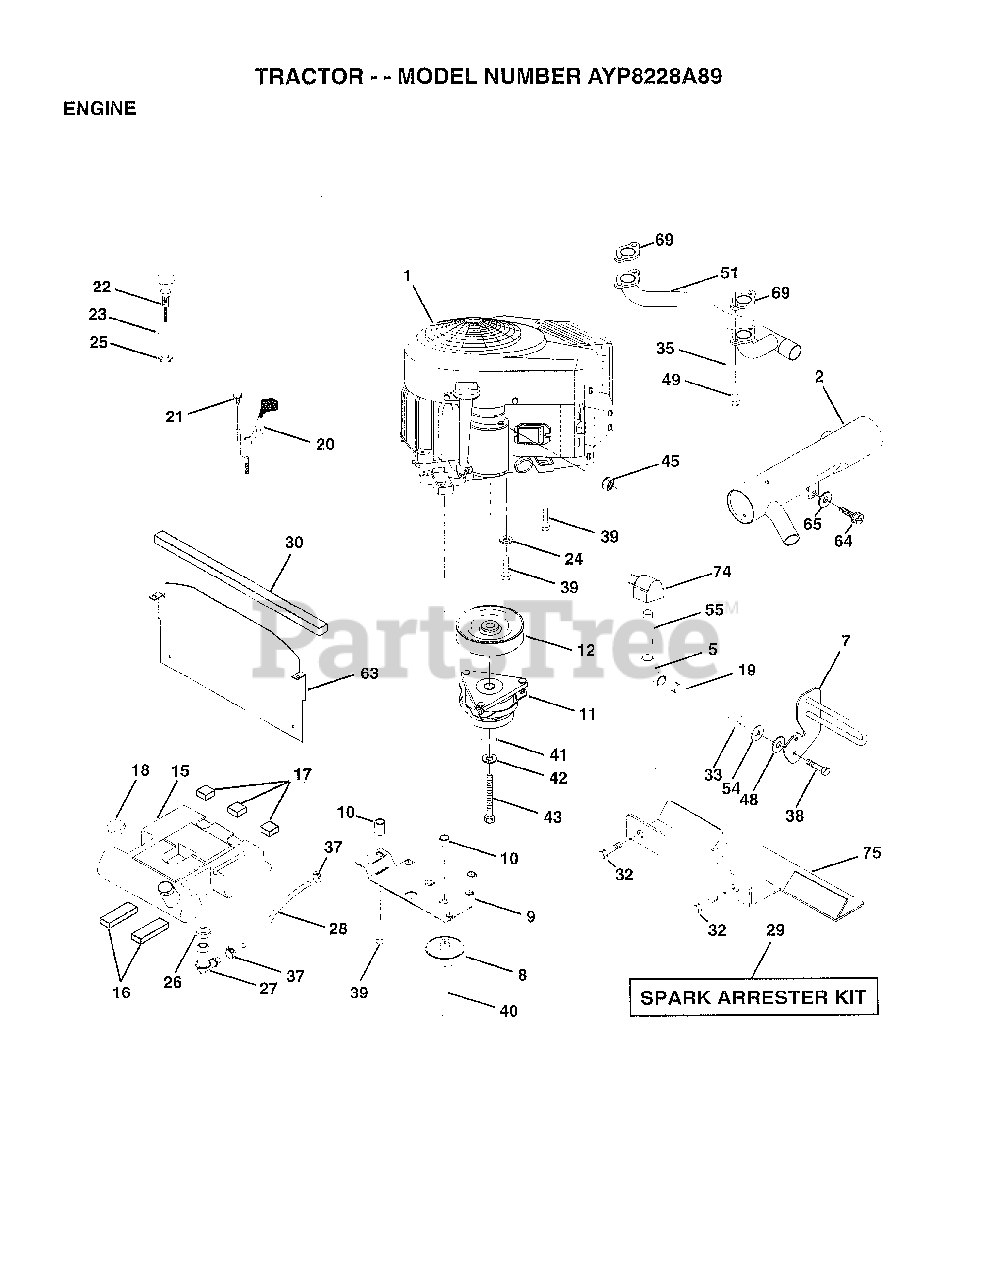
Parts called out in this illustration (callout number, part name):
2	MUFFLER SIDE1-1/8
5	ELBOW
7	GUARD.MUFFLER.ASM
9	KEEPER ASM BELT
10	BUSHING.
12	PULLEY.ENG.CLUTCH
15	TANK FUEL REAR
16	PAD IDLER TI
17	PAD-SPACER LT
18	CAP ASM FUEL
19	PLUG T
21	SCREW LT
22	CHOKE CONTROL
23	WASHER
24	LOCKWASHER
25	"NUT,KEPS 3/8-24IM"
26	BUSHING OUTLET T
27	STEM.TANK.FUEL
29	SPARK ARREST KIT
30	FOAM-STRIP LT
32	SCREW LT
33	NUT
35	LOCKWASHER
37	HOSE CLAMP
38	"BOLT,HEX"
39	SCREW.3/8-16X2.25
40	SCREW.TT.3/8-16X4
41	WASHER
42	LOCKWASHER
43	BOLT.7/16-20X4.25
45	NUT
47	SPACER.ENGINE
48	WASHER T
49	SCREW
51	PIPE.MANIFOLD
54	WASHER
55	PIPE NIPPLE LT
63	HEAT.SHIELD.VGT.
64	SCREW
65	WASHER
69	GASKET MUFFLER
74	ELBOW STREET BASS
75	SHIELD.HEAT.INTEK.VGT
